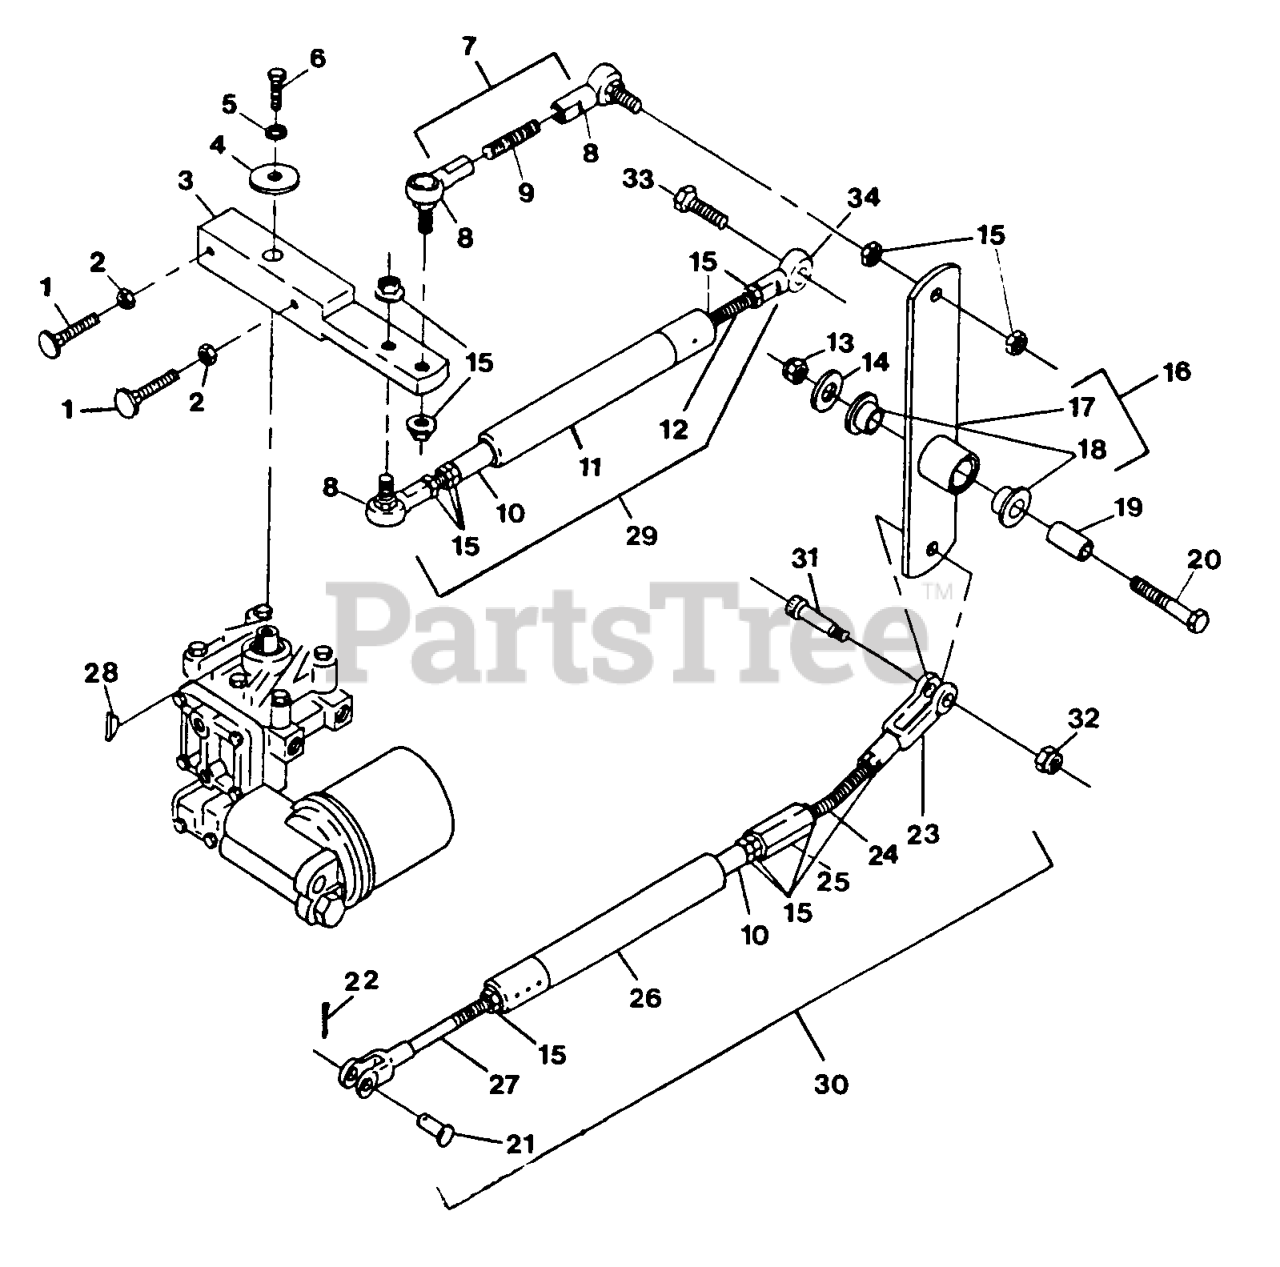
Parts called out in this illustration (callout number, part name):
3	WLD,ARM TRANSAXLT
4	WASHER-RETAINER, PULLEY
5	WASHER-LOCK
8	BALLJOINT
9	ROD END PLTD.
10	BUSHING,SPRING GUIDE
12	ROD,END
17	WLD,IDLER LINKAGE
18	BEARING-CONTROL
19	BUSHING,MOTION LEVER
21	PIN-CLEVIS
23	YOKE-ADJUSTABLE
27	LINKAGE-CLEVIS .31
31	SCREW-HSH
34	BALLJOINT-RH
